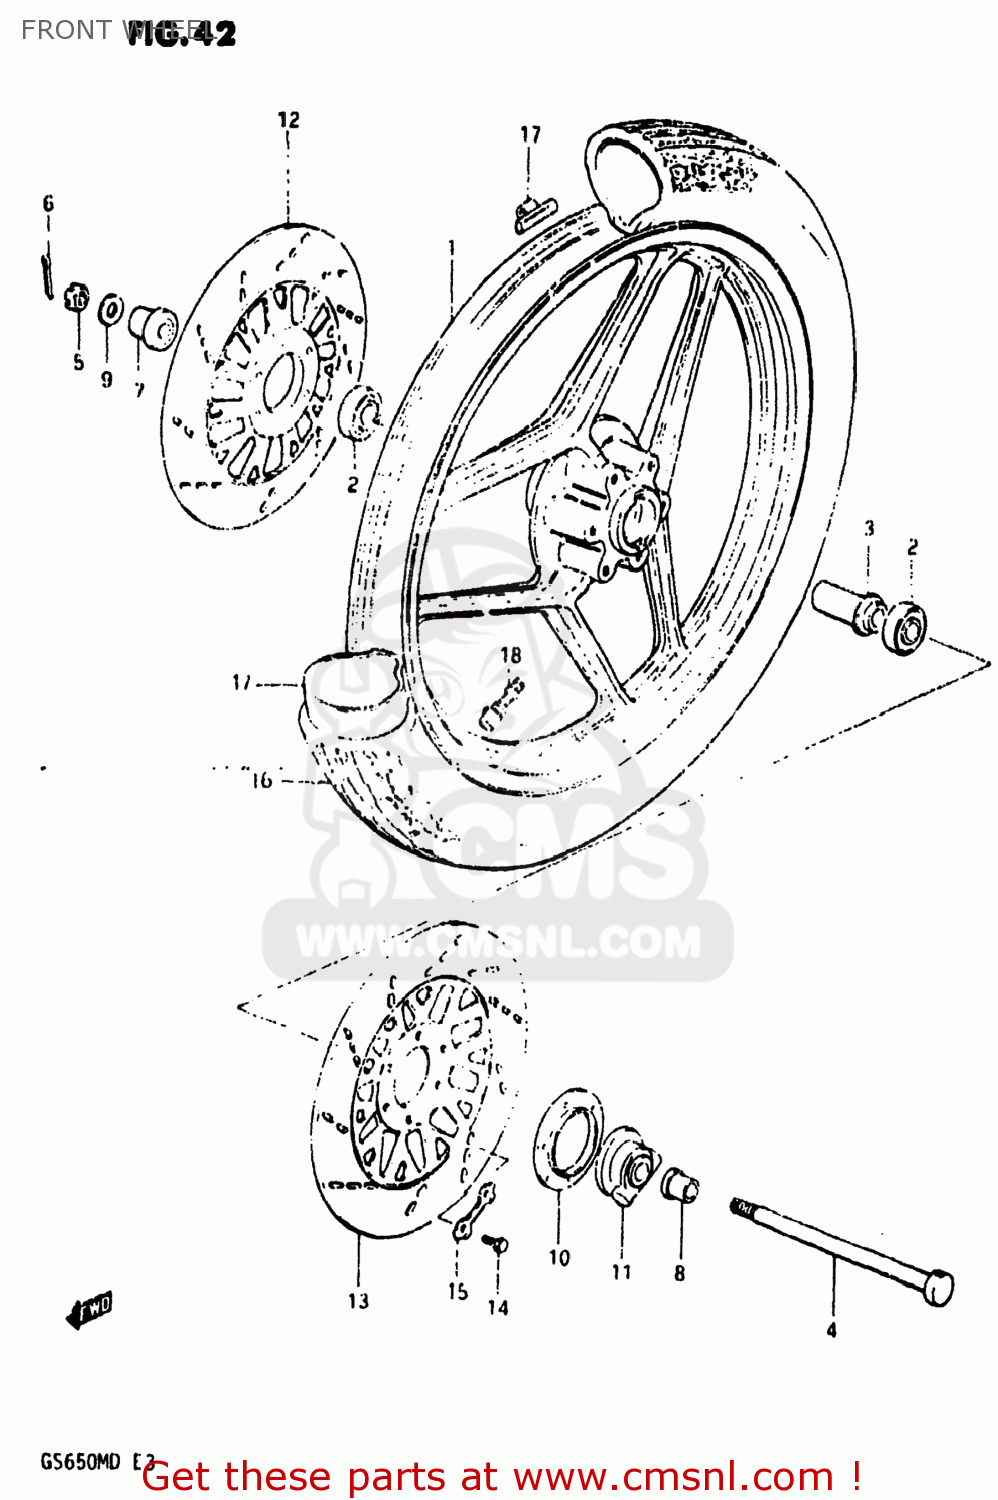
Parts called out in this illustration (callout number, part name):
1	WHEEL,FRONT
2	BEARING
3	SPACER,FR HUB BEARING
4	AXLE,FRONT
5	NUT 12MM
6	COTTER PIN
7	SPACER,FR HUB BEARING,R
8	SPACER(15X22X30)
9	WASHER
10	DUST SEAL,SPEEDOMETER GEAR BOX
11	BOX ASSEMBLY,SPEEDOMETER GEAR
12	DISC,BRAKE
13	DISC,BRAKE
14	BOLT(8X28)
15	WASHER
16	TIRE,FRONT
17	BALANCER,WHEEL
18	VALVE ASSEMBLY,WHEEL RIM,J
